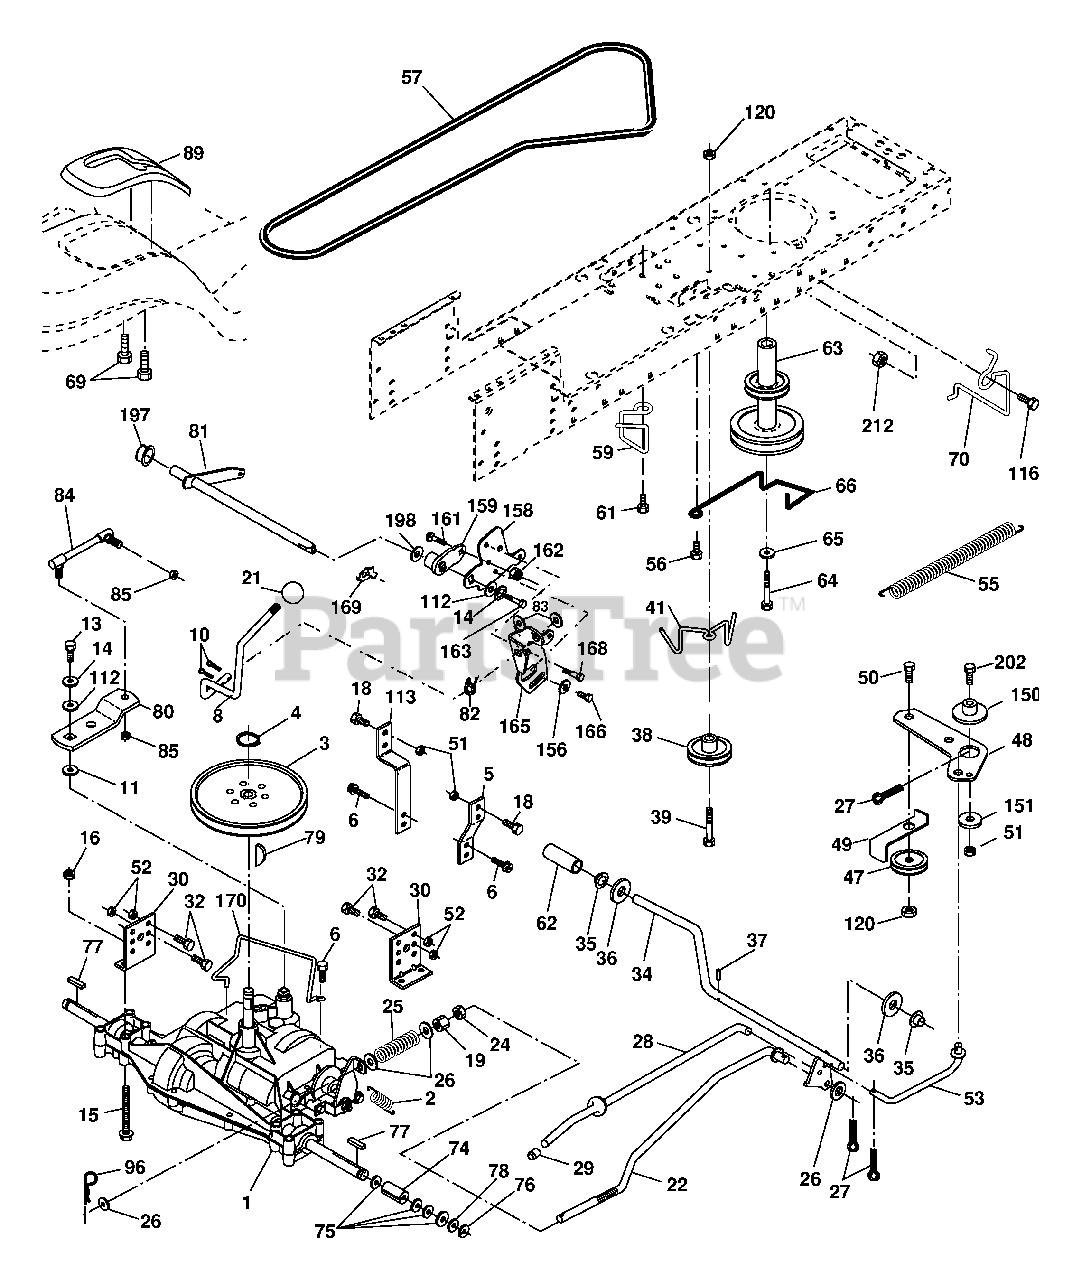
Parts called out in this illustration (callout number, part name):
1	Transaxle Peerless (206-545C) (Order parts from transaxle manufacturer)
2	Spring Return Brake T/a Zinc
3	Pulley Transaxle 18" tires
4	Ring Retainer # 5100-62
5	Strap Torque 30 Degrees
6	Screw 5/16-18 X 3/4
8	Rod Shift Fender Adjust Lt
10	Pin Cotter 1/8 X 1 Cad
11	Washer Plate Shf 388 Sq Hole
13	Bolt 1/4-28 Unf Gr. 8 W/Patch
14	Washer Lock Hvy Helical
15	Bolt Hex FLGHD 5/16-18 Gr. 5
16	Nut Lock Hex w/ins 5/16-18
18	Bolt, Fin Hex 3/8-16 unc x 1 Gr. 5
19	Nut Lock 3/8-16 Unc
21	Knob
22	Rod Brake Blk Zinc 26 840
24	Nut Hex Jam 3/8-16 unc
25	Spring Rod Brake 2 00 Zinc
26	Washer 13/32 x 13/16 x 16 Ga.
27	Pin Cotter 1/8 x 3/4 Cad
28	Rod Brake Parking LT/YT
29	Cap Brake Parking
30	Bracket Mtg Transaxle
32	Bolt Hex Hd 5/16-18 unc x 3/4
34	Shaft Asm Pedal Foot
35	Bearing Nylon Blk 629 Id
36	Washer 21/32 x 1 x 16 Ga.
37	Pin Roll 3/16 X 1"
38	Pulley Composite Flat
39	Bolt RDHD 3/8-16 unc x 2-3/4 Gr. 5
41	Keeper Belt Flat Idler
47	Pulley Idler V Groove Plastic
48	Bellcrank Asm
49	Retainer Belt Style Spring
50	Bolt Carr. Sh. 3/8-16 x 1-1/2 Gr. 5
51	Nut Crownlock 3/8-16 unc
52	Nut Crownlock 5/16-18 unc
53	Link Clutch
55	Spring Return Clutch 6 75
56	Screw 3/8-16 x 1-1/4
57	V-Belt Ground Drive
59	Keeper Belt Span Ctr
61	Screw 3/8-16 x .875
62	Cover Pedal Blk Round
63	Engine Pulley
64	Bolt Hex
65	Washer Lock Hvy Hlcl Spr 7/16
66	Keeper Belt Engine Foolproof
69	Screw Hex wsh Hi Lo 1/4 x 1/2 unc
70	Guide Belt Mower Drive RH
74	Spacer Axle
75	Washer 25/32 x 1 1/4 x 16 Ga.
76	E-ring #5133-75
77	Key Square 2 0 x 1845/ 1865
78	Washer 25/32 x 1-5/8 x 16 Ga.
79	Key Woodruff #9 3/16 x 3/4
80	Arm Shift
81	Shaft Asm Cross Tapered PMST/ 20
82	Spring Torsion T/a
83	Washer 17/32 x 3/4 x 16 Ga.
84	Link Transaxle PMST/18" Zinc
85	Nut Lock Center 1/4 - 28 FNTHD
89	Console Shift STLT
96	Retainer Spring 1"
112	Washer
113	Strap Torque LT
116	Bolt Rdhd Sq Neck 3/8-16 x 1
120	Nut Lock Flg. 3/8-16 unc
150	Spacer Retainer
151	Washer 13/32 x 2 x 10
156	Washer Srrted 5/16ID x 1.125
158	Bracket Shift Mount
159	Hub Tapered Flange Shift Lt
161	Bolt Rdhd Sqnk 1/4-20 x 3/4
162	Nut Crownlock 1/4-20 unc
163	Bolt Hex Fin 1/4-20 unc x 1 Gr. 5
165	Bracket Pivot Lever
166	Screw 5/16-18 x 5/8
168	Bolt Shoulder 5/16-18 x .561
169	Plate Fastening
170	Keeper Belt Transaxle Gear
197	Nyliner Snap-In
198	Washer Nyliner
202	Bolt Rd Hd 3/8-16 unc x 1-3/4 Gr. 5
212	Nut Hexflange Lock
